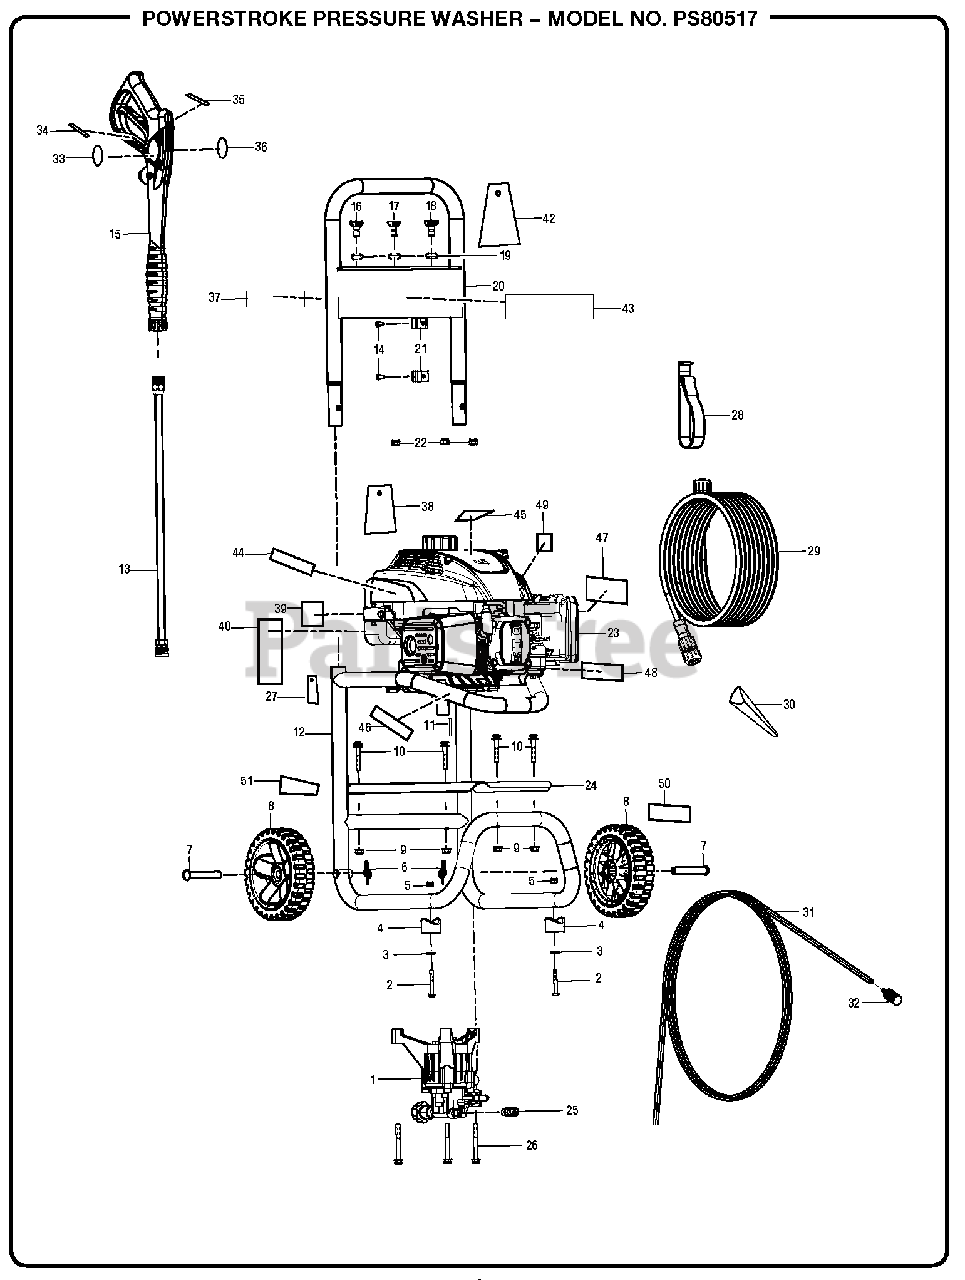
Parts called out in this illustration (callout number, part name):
2	Screw (1/4-20 x 2 in., T30 Torx Hd.)
3	Washer (1/4 in.)
5	Lock Nut (1/4-20)
6	Axle Clip
7	Axle
9	Hex Nut (M8 x 1.25)
10	Bolt (M8 x 45 mm Flange Hd.)
11	Output Shaft Key (40 mm)
12	Main Frame Assembly
13	Extension Wand
14	Screw (12-14, Type B)
15	Trigger Handle w/Logo
16	Soap Nozzle
17	25deg Nozzle
18	40deg Nozzle
19	Nozzle Holder
20	Handle Assembly
21	Spring Clip
22	Lock Nut (M8)
23	Engine (Rato)
24	Engine Plate
25	Thermal Release Valve
26	Bolt (M8 x 70, Flange Hd)
27	Add Oil Hang tag
28	Wand Holder Strap
29	Hose (25 ft.)
31	Chemical Siphon Tube
32	Chemical Siphon Filter
33	Gun Warning SP Label
34	Label (Wand Logo)
35	PowerStroke Wand Warning
36	Gun Rating
37	Quick Start Label
38	Danger Hang tag
39	No Oil To Gas Label
40	E85 Label
41	Danger Label
42	Nozzle Hang Tag
43	Performance Label
44	Lubricant Label
45	Logo and Nozzle Label
46	Hot Surface Label
47	Combustion Label
48	Fuel On / Off Label
49	Choke Label
50	Data Label
51	Add Oil Label
